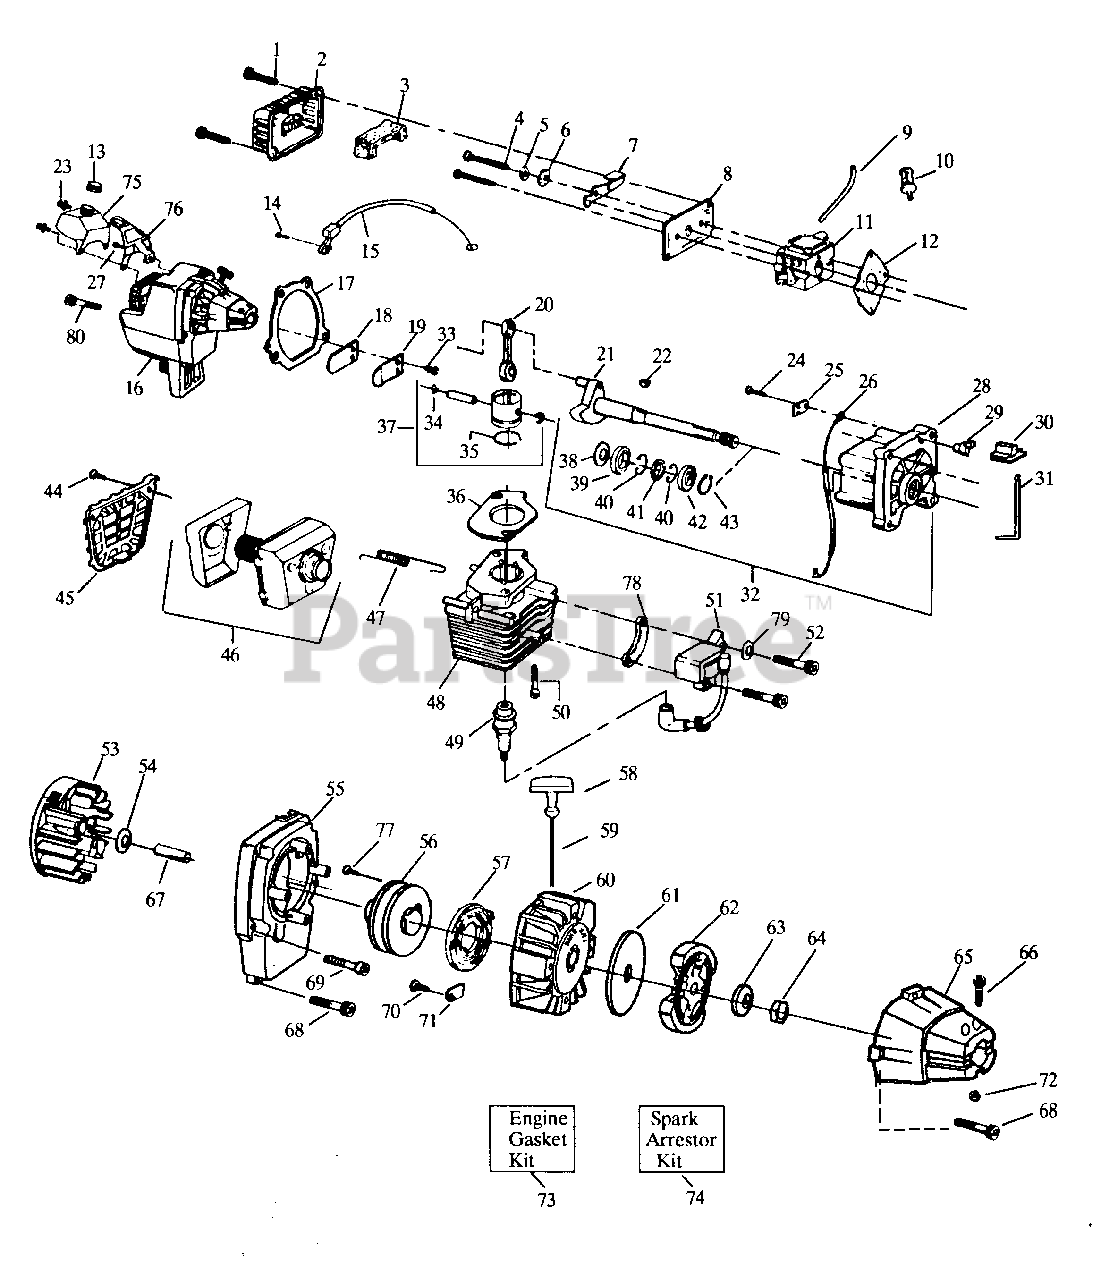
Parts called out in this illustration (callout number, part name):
2	Air Filter Cover
3	Air Filter
5	Spacer
6	Wave Washer
7	Choke Shutter
8	Air Filter Plate
9	Fuel Line
10	Fuel Pick-up Ass'y.
11	Carburetor
12	Carburetor Gasket
13	Fuel Cap Ass'y.
15	Throttle Cable Ass'y.
17	Crankcase/Shroud Gasket
19	Reed Stop
20	Connecting Rod Ass'y. (Inc. Bearings)
21	Crankshaft Ass'y.
22	Flywheel Key
25	Switch Insulator
26	Lead Wire
27	Screw
28	Crankcase Ass'y. (Inc. #39-42)
29	Switch Ramp
30	Switch Button
31	Switch Spring
32	Crankcase & Crankshaft Ass'y (Inc. 21,28,38, 43)
34	Piston Pin Retainer
35	Piston Ring
36	Cylinder Gasket
37	Piston Kit (Inc.34,35, & pin)
39	Inner Bearing
40	Retaining Ring
41	Crankshaft Seal
42	Outer Bearing
43	Crankshaft Retaining Ring
45	Muffler Guard
46	Muffler Kit
47	Muffler Attachment Spring
48	Cylinder
49	Spark Plug
51	Ignition Module Kit
53	Flywheel Ass'y.
54	Washer
55	Fan Housing
56	Starter Pulley
57	Starter Spring
58	Starter Handle
59	Rope Kit
60	Pulley Housing Ass'y.
61	Clutch Washer
62	Clutch Ass'y. Kit
65	Clutch Housing
71	Retainer
73	Engine Gasket Kit
74	Spark Arrestor Kit
75	Fuel Tank Ass'y.
76	Fuel Tank Mtg. Bracket
77	Screw (Inc. in Starter Pulley Kit)
